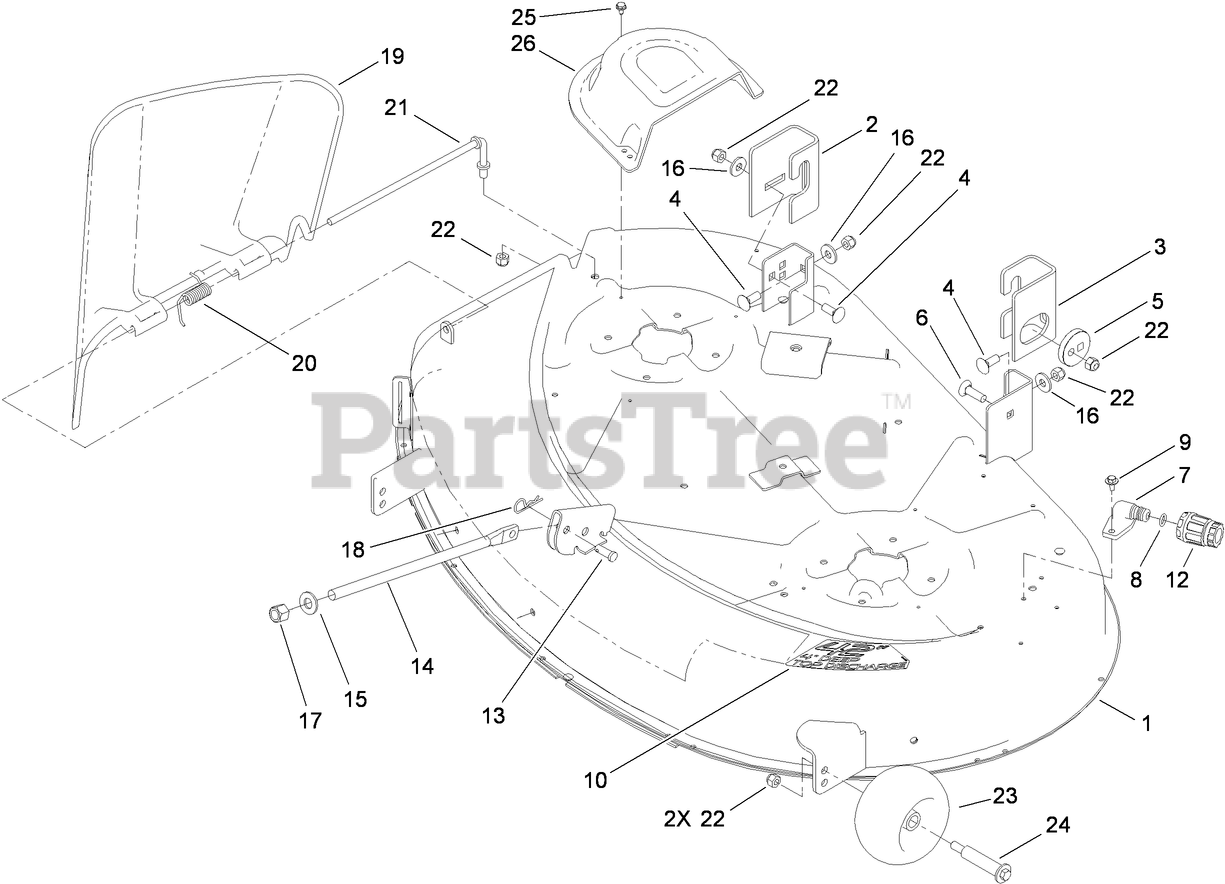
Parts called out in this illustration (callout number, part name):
2	BRACKET-HANGER, RIGHT REAR
3	BRACKET-HANGER, LEFT REAR
4	BOLT-CARR
5	ECCENTRIC
6	SCREW-CARR
8	O-RING
9	SCREW-HHFTF
12	CONNECTOR-HOSE
13	PIN-CLEVIS
14	ROD-LIFT
15	WASHER-THRUST
16	WASHER-HARDENED
17	NUT-LOCK, NI
18	PIN-HAIR
19	DEFLECTOR
20	SPRING-TORSION
21	ROD-PIVOT
22	NUT-LOCK, NI
23	ROLLER-SCALP, ANTI
24	BOLT-SHOULDER
25	SCREW-HWHTF
26	COVER-BELT
